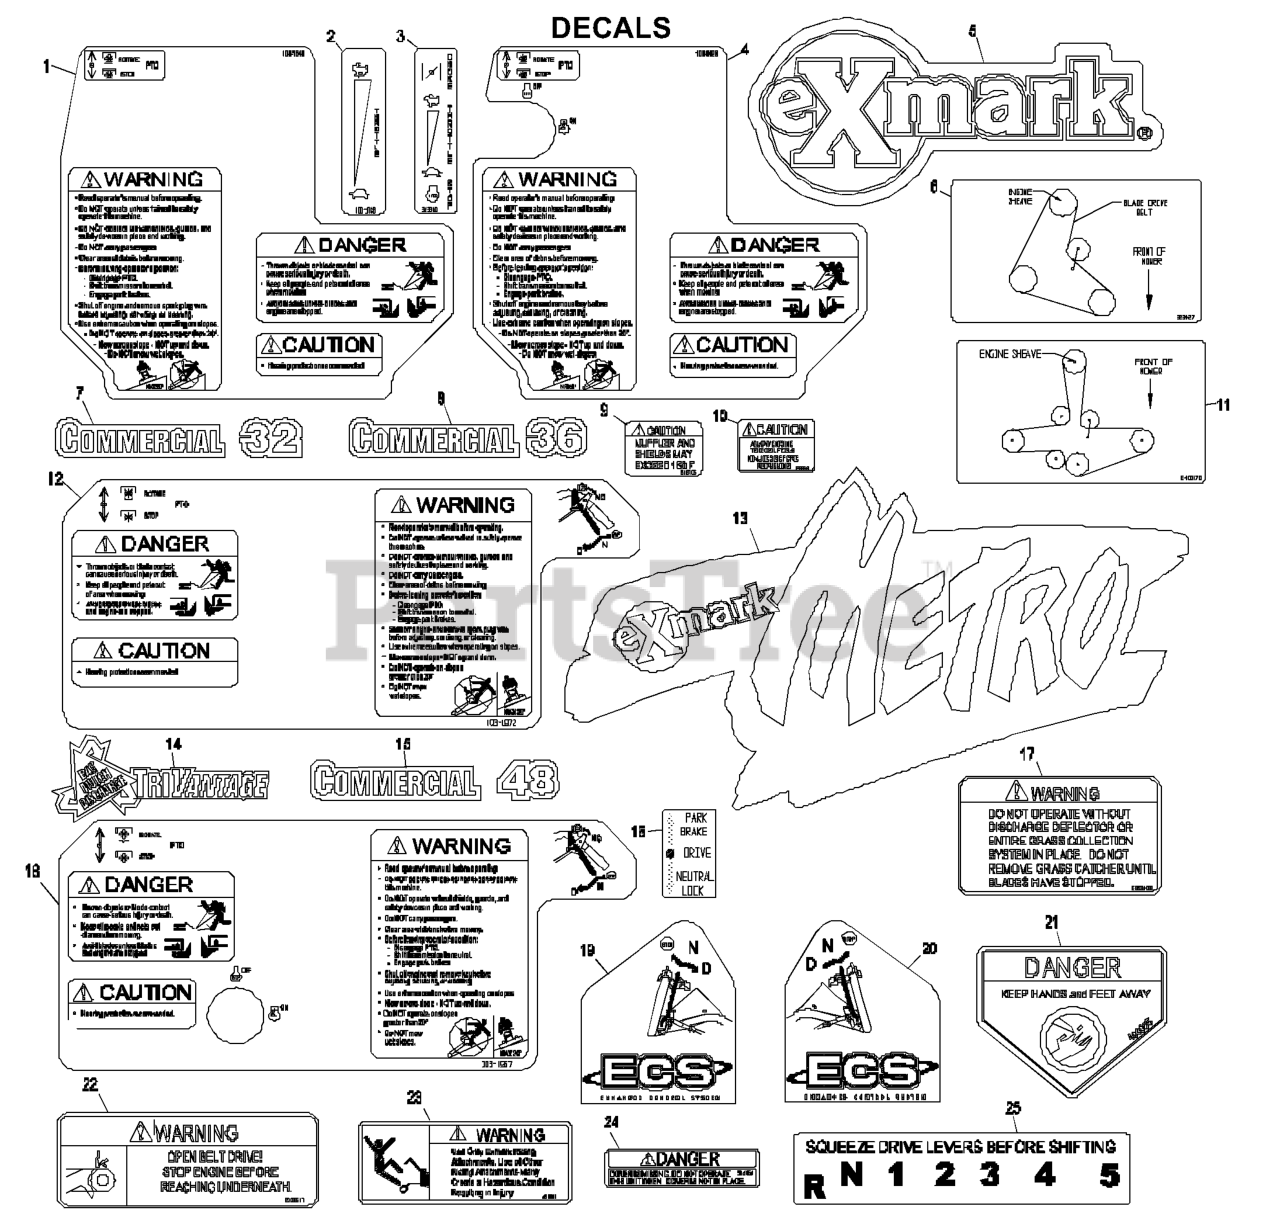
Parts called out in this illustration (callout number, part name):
1	DECAL,METRO ECS CONSOLE
2	DECAL,THROTTLE ONLY
4	DECAL,METRO ECS CONSOLE
6	DECAL,BELT ROUTING 32/36
7	DECAL,COMMERCIAL 32
8	DECAL,COMMERCIAL 36
12	DECAL,CONSOLE
15	DECAL,COMMERCIAL 48
16	DECAL,NEUTRAL/BRAKE
17	DECAL-WARNING, DISCHARGE
18	DECAL,CONSOLE
19	DECAL,RH ECS INSTRUCTION
20	DECAL,LH ECS INSTRUCTION
21	DECAL-DANGER
22	DECAL,BELT DRIVE
23	DECAL,SULKY WARNING
24	DECAL-COVER, MISSING
25	DECAL,SHIFTER
